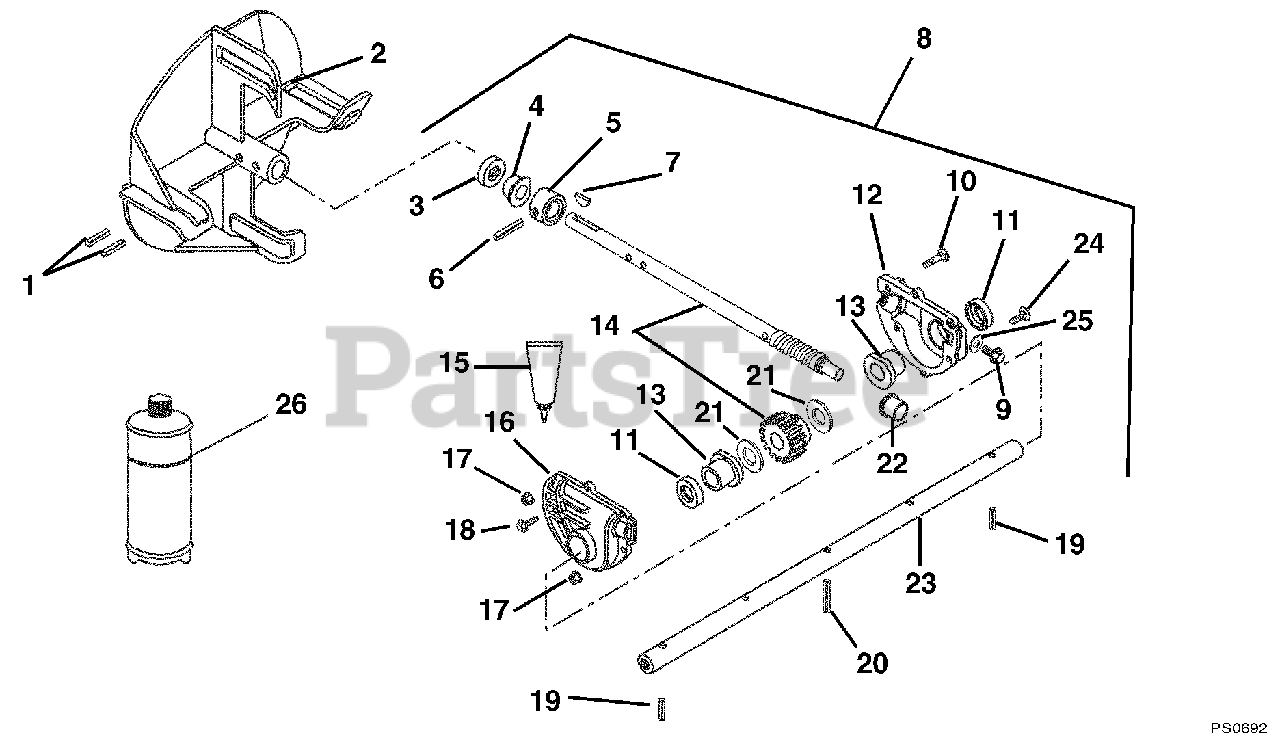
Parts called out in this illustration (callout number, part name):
1	PIN-ROLL .250X1.75
2	FAN - 12"
3	SEAL-OIL .750X1.375X.250
4	BSHG-FLG .750X1.000X.750X1.250
5	THRUST COLLAR
6	PIN-GRV .188X1.25 TP A
7	KEY-WDRF .188X.875X.375 SAE11
8	CASE, GEAR-LARGE BORE-28"-ALUM
8	GEAR CASE-LRG BORE-ALUM.- 24"
9	@SCR-TAP .38-16X.50 HWH TR YWZ
10	@BLT-RDHDSQNK .25-20X1.25 G5YZ
11	SEAL-OIL 1.000X1.375X.250
12	CASE, GEAR-LH-LARGE BORE-ALUM.
13	BSHG-FLG 1.00X1.12
14	WORM SHAFT & GEAR ASSY
15	LOCTITE GASKET 518--850CC CRTG
16	CASE, GEAR-RH-LARGE BORE-ALUM.
17	@NUT-SPNLK-FLG .25-20 YWZC
18	SCR-TAP 10-24X.75 HWH TR YWZC
19	PIN-ROLL .188X1.50
20	PIN-GRV .313X1.44 TP C
21	WSHR-HRD-THRS 1.007X1.542X.062
22	BSHG-FLG .502X1X.750
23	SHAFT, RAKE - 28"
23	SHAFT, RAKE - 24"
24	@BLT-RDHDSQNK .25-20X1.00 G5YZ
25	WSHR-FIBER .437X.656X.032
26	ARIENS 16 OZ.BOTTLE OF L2 LUBE
